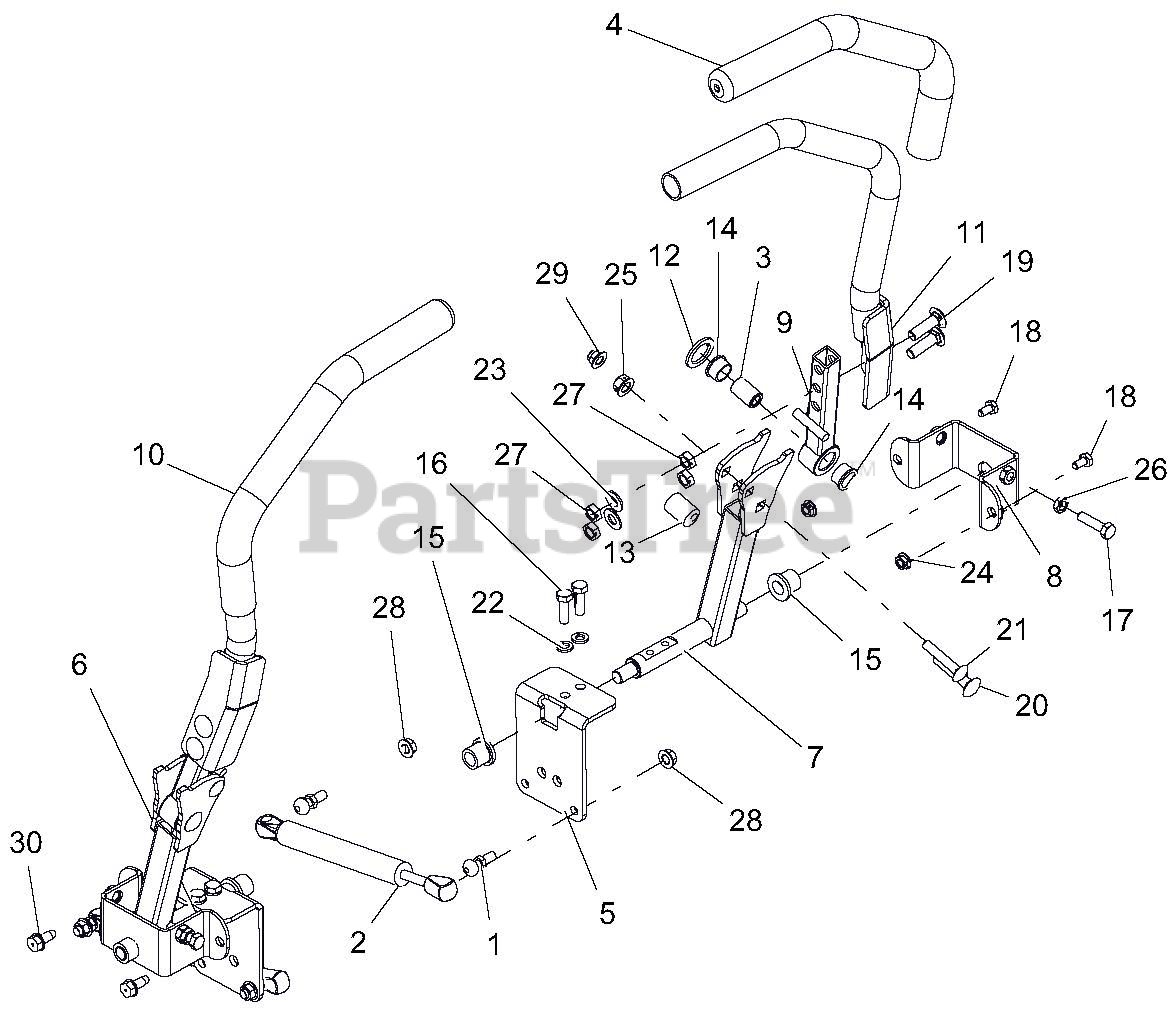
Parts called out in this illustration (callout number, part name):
1	STUD-BALL
3	SPCR, .375X.625X.970
4	GRIP, HANDLEBAR 15" FOAM
5	BRKT, STEERING
6	WLDMT, LOWER STEERING ARM
7	WLDMT, LH LWR STEERING ARM
8	WLDMT, BRKT STEERING
9	WLDMT, UPPER CONTROL ARM
10	WLDMT, STEERING HANDLE RH
11	WLDMT, STEERING HANDLE LH
12	WSHR, FRICTION .875X1.25X.10
13	BSHG, ECCENTRIC .328 X .750 X .970
14	BSHG, .625X.75X.450X.875
15	BSHG, FLANGE .515 X .750 X .745 X 1.00 NYLON
16	BLT-HEX .31-18X1.00 GR8 YWZC
17	BLT-HEX .31-18X1.25 GR5 YWZC
18	BLT-HEX .25-20X.50 GR5 YWZC
19	BLT-RHDSSQNK .38-16X1.25 G5YZ
20	BLT-RHDSSQNK .38-16X1.75 G5YZ
21	BLT-RDHDSQSHNK .31-18X1.75 YWZC
22	WSHR-LK .31X.078 REG YWZC
23	WSHR-FL-STL.406X.812X.065 YWZ
24	NUT, LK-CTR-FLG .25-20 YWZC
25	NUT, LK-CTR-FLG .38-16 YWZC
26	NUT, JAM .312-18 YWZC
27	@NUT-LK-CTR-JAM .375-16 YWZC
28	NUT, LK-TOP-FLG .312-18 YWZC
29	NUT-LK-NYL-FLG .31-18 YWZC
30	SCR-TAP .31-18X.75 HWH TR YWZ
